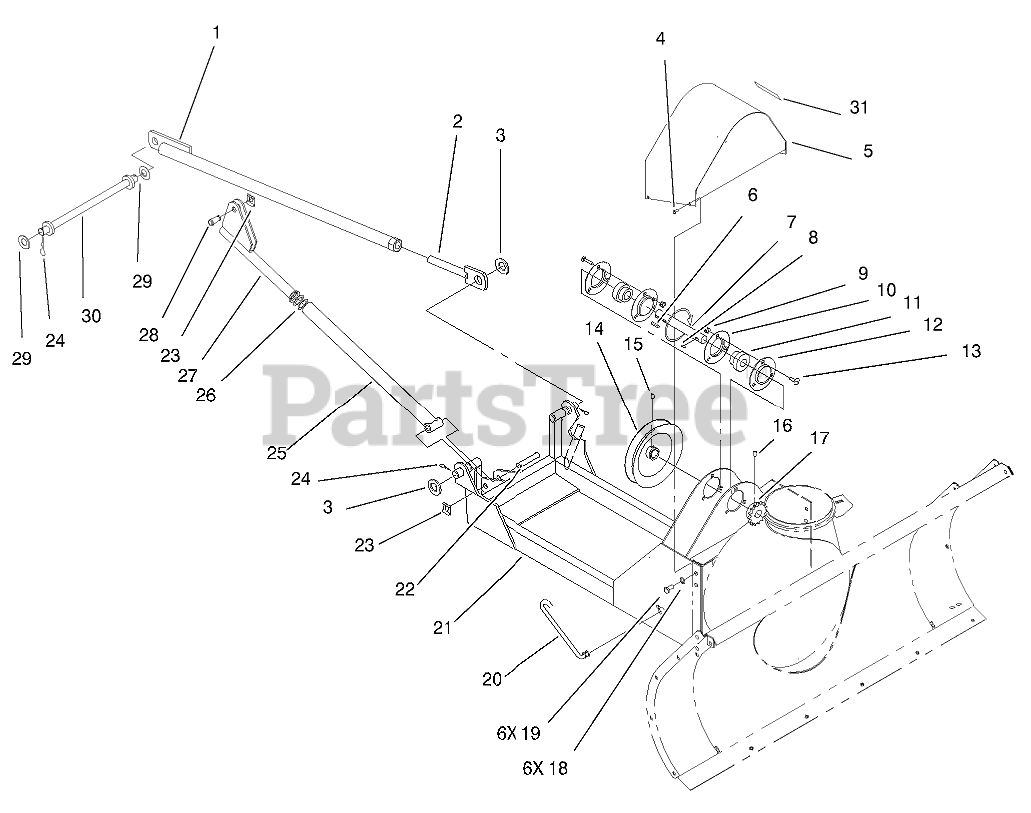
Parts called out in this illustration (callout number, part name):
1	BRACE ASM
2	ADJUSTER ASM
3	WASHER-FLAT
4	SCREW-TAPTITE
5	PULLEY COVER ASM
6	KEY
7	Shaft-Jack
8	KEY-HI PRO
9	NUT-LOCK, NI
10	FLANGE-RELUBE
11	BEARING AND COLLAR
12	Flange
13	BOLT-CARR
14	PULLEY-DRIVE
15	SCREW-SQH
16	SCREW-SET
17	SPROCKET-15 T
18	WASHER-LOCK
19	SCREW-HH
20	LINK-SPRING TENSION
21	FRAME ASM
22	PIN-CLEVIS
23	CLIP-PIN
24	PIN-COTTER, HAIR
25	ROD-LIFT
26	WASHER-FLAT
28	PIN-CLEVIS
29	WASHER-FLAT
30	LINK ASM
31	DECAL-IMPORTANT
